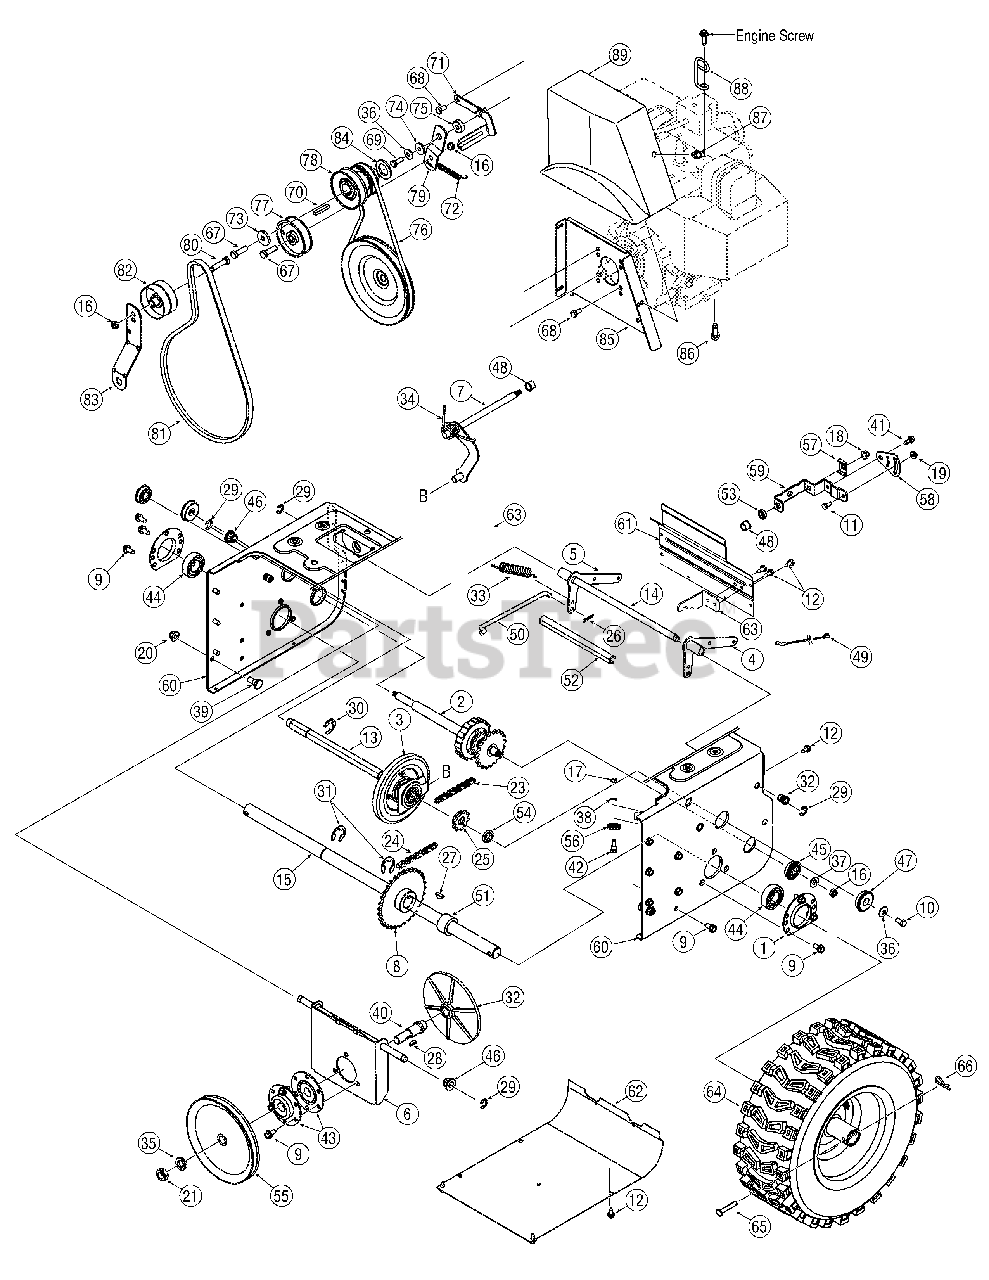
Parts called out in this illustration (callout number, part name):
1	Housing, Bearing
2	Shaft Assembly
3	Assembly, Friction Wheel
3	Wheel, Friction, Bonded
3	Screw, Hex Wash
7	Rod Assembly, Shift
8	Sprocket, 32T
9	TT Screw, 5/16-18 x .750
10	Screw, Hex Cap Lock,
11	Screw, 1/4-20 x .620
12	Screw, Hex Wash.
13	Shaft, Hex Drive
14	Shaft, Actuator
15	Axle, .995 x 25.35
16	Nut, Hex Insert Jam Lock
17	Nut, Hex, 1/4-28 GR5
18	Nut, Hex Flnge Insert Lk
19	Flange, Lock Nut, 1/4-20
20	Nut, Hex Flnge Insert Lk
21	Nut, Hex Insert Jam Lk
22	Nut, Insert 3/8-16
23	Chain, Endless, #41 x 36L
24	Chain, #420 x 40L
25	Sprocket, #41 x 10T
26	Pin, Internal Cotter
27	Key, Woodruff
28	Key, Hi-Pro, 3/16 x 5/8
29	E-Ring
30	Ring, Retaining
31	Ring, Retainer
32	Plate, Drive
33	Spring, Extension
34	Spring, Torsion
35	Washer, Lock, 5/8
36	Washer, Bell., .34 x .872 x .06
37	Washer, .406 x .875 x .059
38	Washer, Lock, 1/4
39	Screw, Shoulder, .498 x .34
40	Spindle, Drive Plate
41	Screw, Shoulder, .368 x .113
42	Screw, Hex Shldr., 1/4-28
43	Assembly, Bearing/Housing
44	Bearing, Self Aligning
45	Bearing, Ball
46	Bearing, Hex Flange
47	Bearing, Ball
48	Bushing, Flange, .5 ID x .627 OD
49	Cable, Auger Idler
50	Rod, Drive Clutch
51	Spacer., 1.0 ID x 1.50 OD
52	Spacer, .51 ID x 7.895 Lg.
53	Spacer, .515 ID x .750 OD
54	Spacer, .675 x 1.0 x .23
55	Pulley, Drive
56	Roller, Cable
57	Bracket, Spacer, Shft.
63	Bracket, Planetary Lock
64	Rim Assembly
65	Pin, Clevis
66	Pin, Internal Cotter
67	Screw, 3/8-14 x 1.25 GR8
68	Screw, 5/16-24 x .625
69	Screw, Hx Cap 5/16-24
70	Key, Square, 1/4 x 1.5
72	Spring, Extension
73	Washer, Flat, .406 x 1.25
74	Spacer, Shoulder
75	Spacer, .33 ID x 1.01 OD x .36
76	V-Belt, 3/8 x 34.4
77	Pulley, Flat Idler, 3.0 OD
78	Pulley, Dbl, 3.25 OD
79	Bracket, Idler, Drive
80	Screw, 3/8-24 x 1.50
81	V-Belt, 1/2 x 44.0
82	Idler, Flat, 2.75 OD
83	Bracket, Idler, Auger
84	Spacer 1.02 x 1.63 x .1425
86	Screw, 3/8-16 x 1.00
87	Screw, Hx Wash Hd Tapp
88	Guide, Chute Cable
89	Cover, Belt
